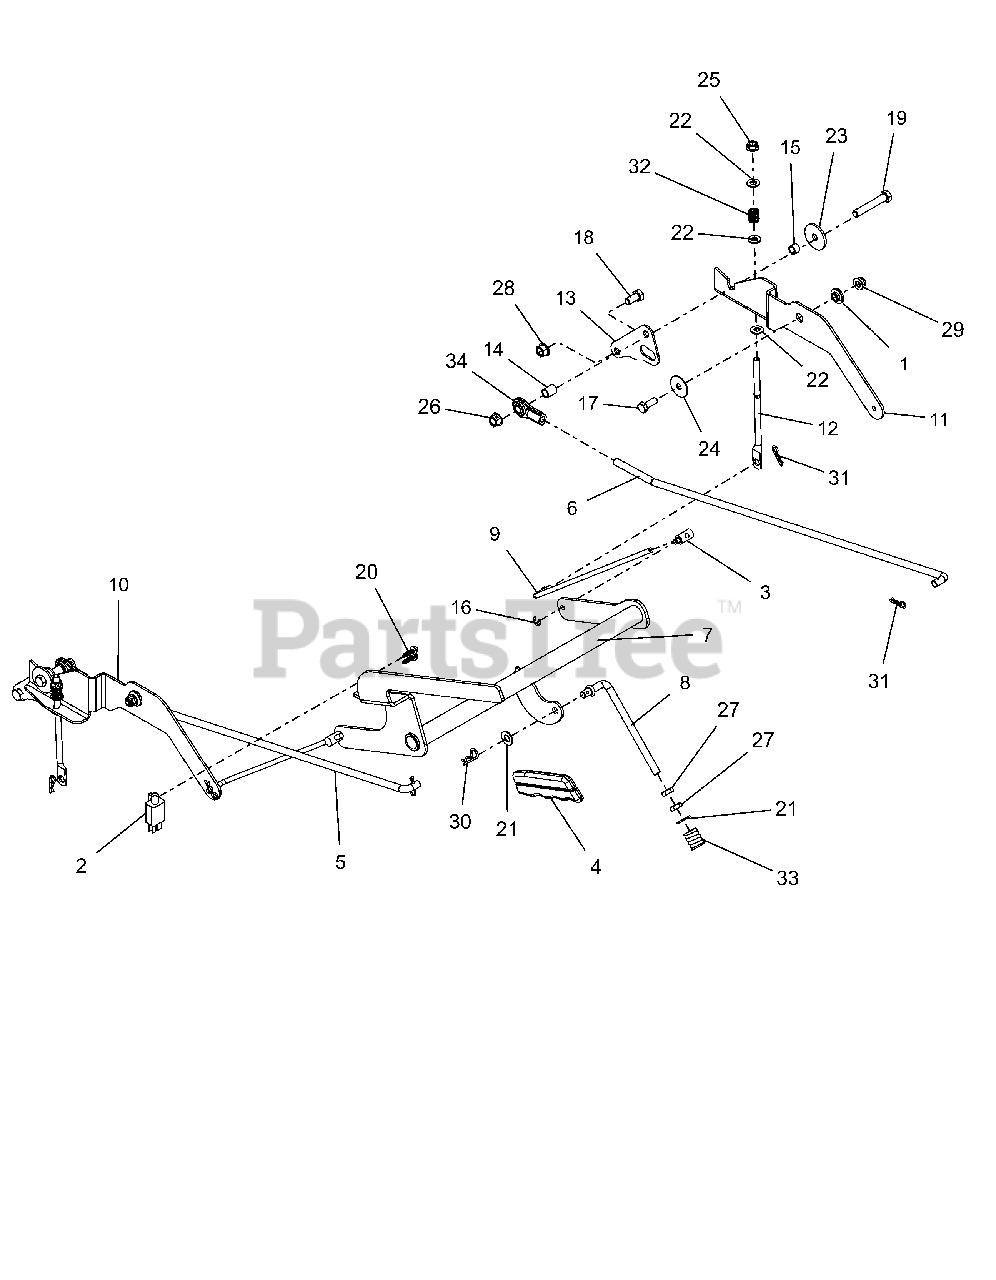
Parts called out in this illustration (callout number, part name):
1	BSHG, FLG .325X.499X.26X.88
2	SWITCH- DOUBLE POLE N.O./N.O.
3	TRUNION, 1/4-20
4	GRIP, PARKING BRAKE (YELLOW)
5	STEERING, LINKAGE RH
6	STEERING, LINKAGE LH
7	WLDMT, BRAKE LEVER
8	LINK, OVER CENTER, PARKING BRK
9	ROD, PARK BRAKE
10	INTERLOCK, RH BRAKE LINK
11	INTERLOCK, LH BRAKE LINK
12	LINK, TRANSAXLE BRAKE
13	PLATE, TRANSAXLE ADAPTOR
14	SPCR, SLV .385X.500X.652
15	SPCR, SLV .385X.500X.350
16	RG-RTNG-EXT .250X.025
17	BOLT-HEX.31-18X.875 YWZC GR5
18	@BLT-HEX .38-16X.75 GR5 YWZC
19	@BLT-HEX .38-16X2.25 GR5 YWZC
20	SCR-TAP #12X.75 BOSS INDHXHD
21	@WSHR-FL-STL.406X.812X.065 YWZ
22	@WSHR-FL-STL.344X.688X.065YWZC
23	WSHR-FL-STL .380X1.50X.125YWZC
24	WSHR-FL-STL .347X1.254X.048YWZ
25	@NUT-LK-CTR-FLG .31-18 YZ GR F
26	NUT-LK-CTR-FLG .38-16 YWZC
27	NUT-HEX-JAM .375-16 YWZC
28	@NUT-LK-TOP-FLG .38-16 YWZC
29	@NUT-LK-NYL-FLG .31-18 YWZC
30	PIN-HAIR CTR .09 X 1.50 YWZC
31	PIN-HAIR INT .08X.18X1.18 YWZC
32	SPRING, COMPRESSION
33	SG-COMP .187X.56X1.62
34	ROD END, .38 RH
